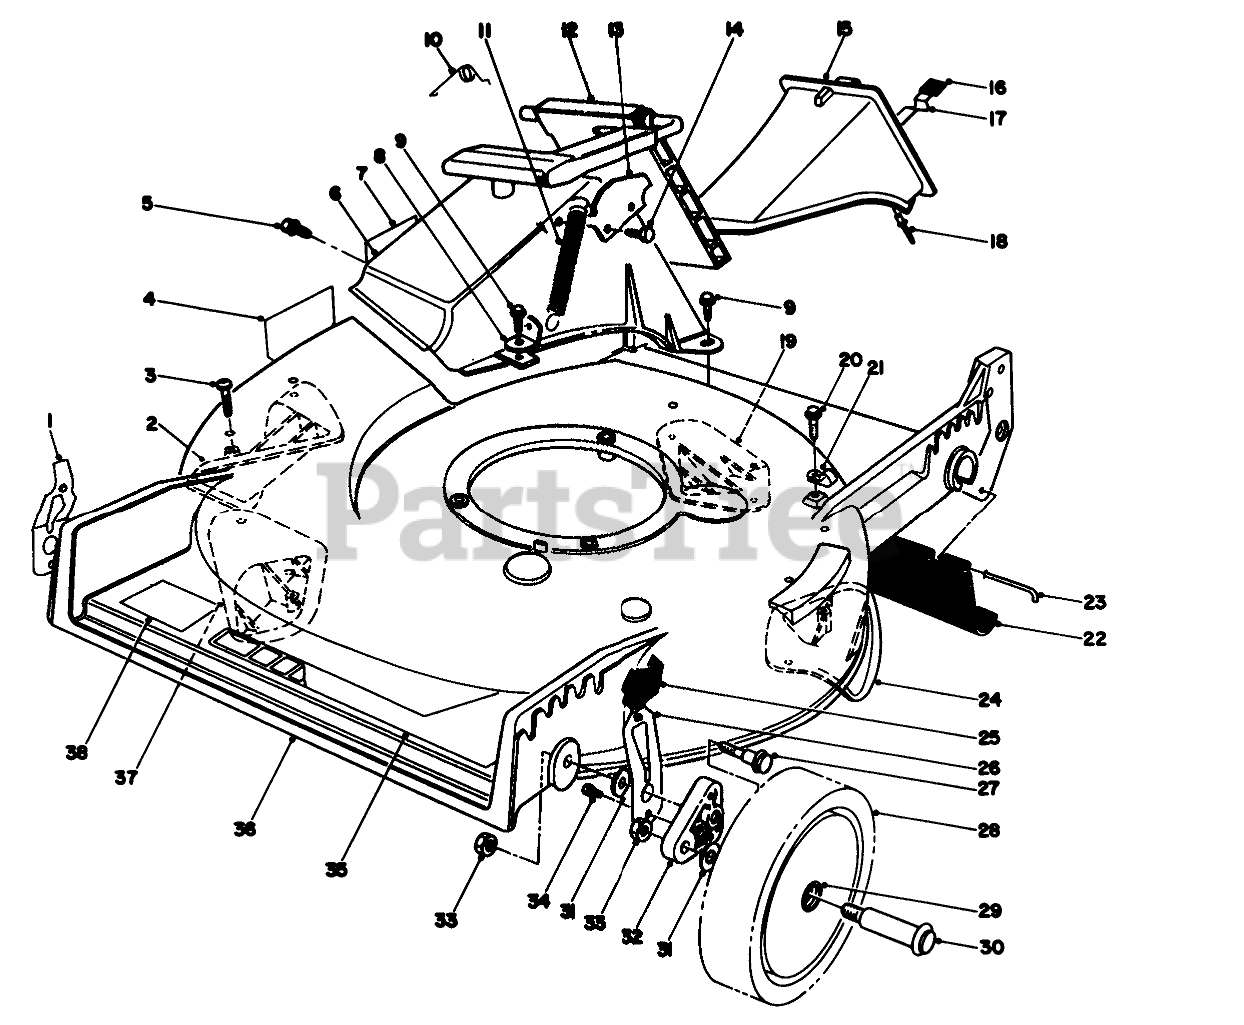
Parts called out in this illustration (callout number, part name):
1	RH SPRING ARM ASSEMBLY
2	KICKER
3	SCREW-PPH
4	DECAL-DANGER
5	SCREW AND WASHER ASM
6	TUNNEL-DISCHARGE
7	Decal-Danger
8	Bracket-Spring
9	SCREW-HWH
10	RETAINER-DOOR
11	SPRING-DOOR
12	OIL CAP ASM
13	DOOR LATCH PLATE
14	SCREW-PLASTITE
15	Plug-Discharge (Incl. Ref . #16-18)
16	GRIP-LATCH
17	LATCH-PLUG, DISCHARGE
18	RIVET-HEAD, FLAT
19	PLATE-KICKER
20	SCREW-HWHTF
21	CLAMP-R
22	HANDLE LATCH
23	ROD-SHIELD
24	KICKER
25	KNOB-ARM
26	LH SPRING ARM ASSEMBLY
27	SCREW-SHOULDER
28	Wheel & Tire Assembly (Incl. Ref. #29)
29	BUSHING
30	WHEEL BOLT
31	WASHER
32	ARM-PIVOT, FRONT
33	Nut
34	SCREW-HWH
35	DECAL - DECK
36	Housing Assembly (Incl. Ref. #2-4, 19, 24 & 37)
37	KICKER
38	DECAL
